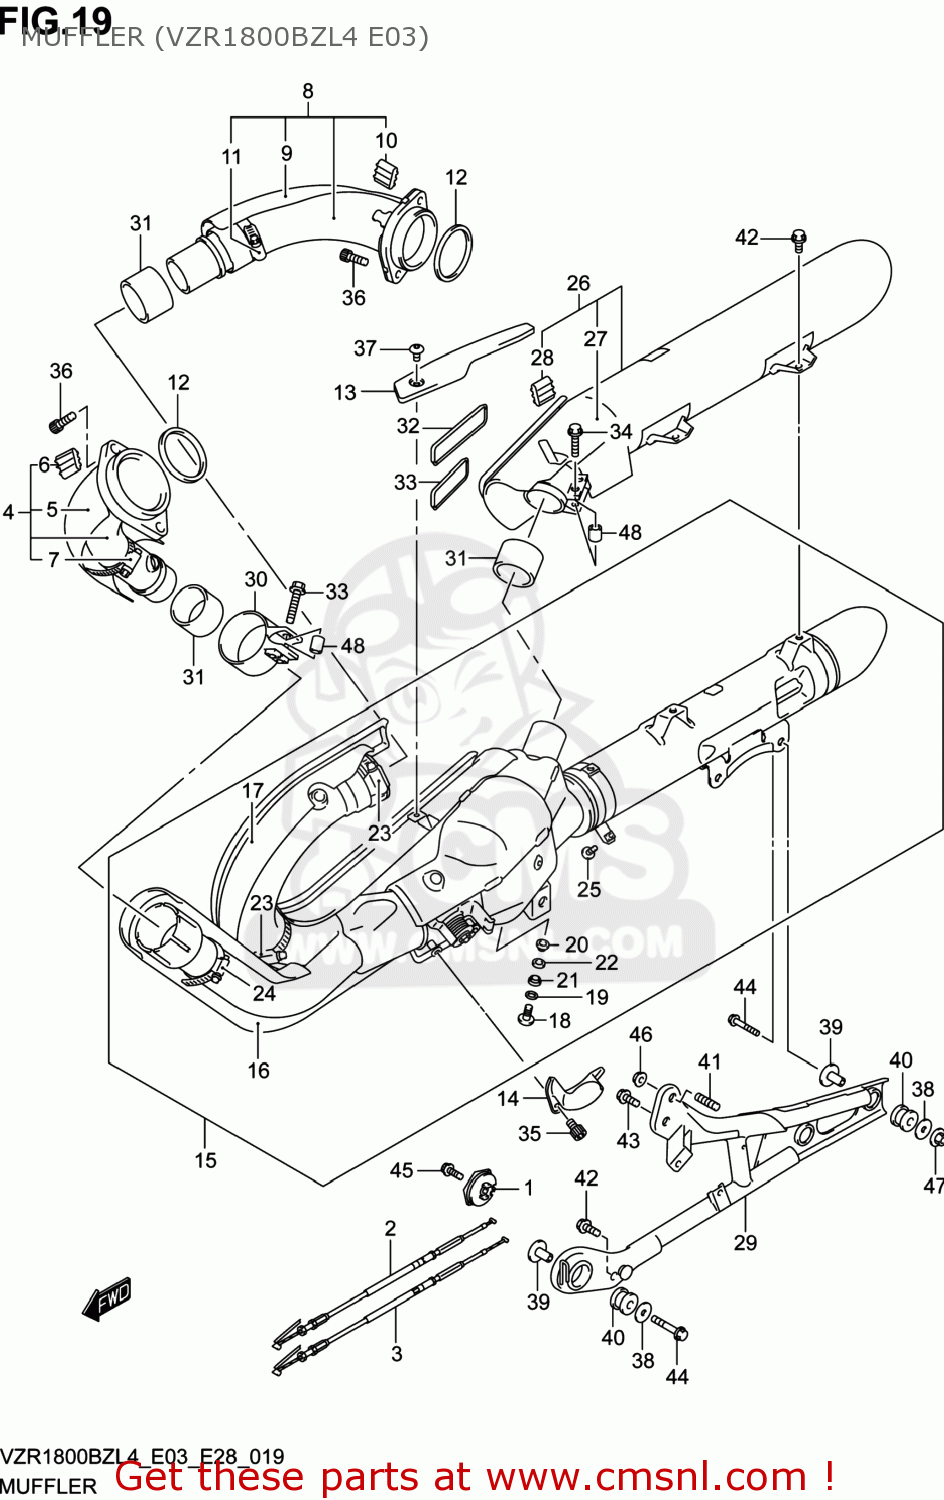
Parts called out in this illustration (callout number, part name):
1	PULLEY,CONTROLLER
2	CABLE,EXHAUST VALVE NO.1
3	CABLE,EXHAUST VALVE NO.2
4	PIPE,EXH FR
5	COVER,EXHAUST FR PIPE
6	GROMMET
7	CLAMP
8	PIPE,EXH RR
9	COVER,EXHAUST RR PIPE
10	GROMMET
11	CLAMP
12	GASKET,EXHAUST PIPE (NAS)
13	COVER,EXH RR UP
14	COVER,EXHAUST VALVE
15	MUFFLER,FR
16	COVER,EXH FR
17	COVER,EXH RR
18	SCREW(6X20)
19	WASHER(6.5X20X1)
20	SPACER(6.2X8.4X10.9)
21	CUSHION
22	CUSHION
23	CLAMP
24	CLAMP
25	BOLT
26	BODY,MUFFLER RR
27	COVER,UPR MUFFLER FR
28	GROMMET
29	BRACKET,MUFFLER SUPPORT
30	CLAMP
31	CONNECTOR,MUFFLER
32	PROTECTOR,UPR
33	PROTECTOR,LOW
34	BOLT(8X35)
35	BOLT(6X12)
36	BOLT(8X25)
37	SCREW(6X10)
38	WASHER(8.5X33X1.5)
39	SPACER(8.6X12X27.1)
40	CUSHION
41	BOLT,STUD
42	BOLT
43	BOLT
44	BOLT
45	BOLT
46	NUT
47	NUT
48	SPACER,MUFFLER
